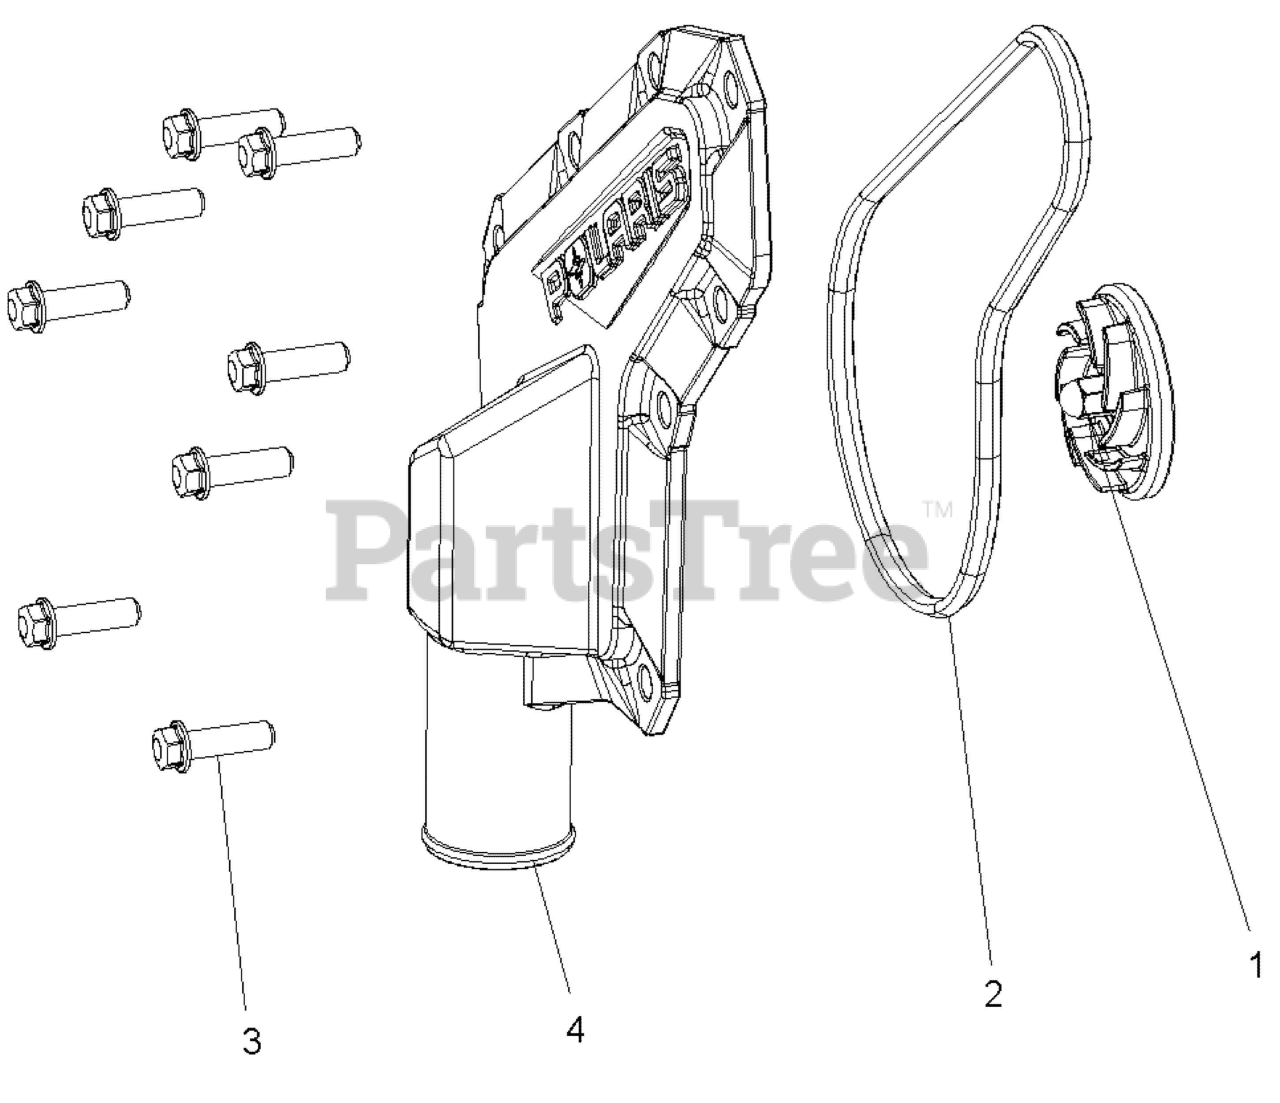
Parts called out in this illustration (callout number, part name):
1	IMPELLER-WATER PUMP 45MM,MACH
2	GASKET-WATERPUMP COVER
3	SCR-M6X20,HXFLG,0600214
4	COVER-WATERPUMP,CAST
